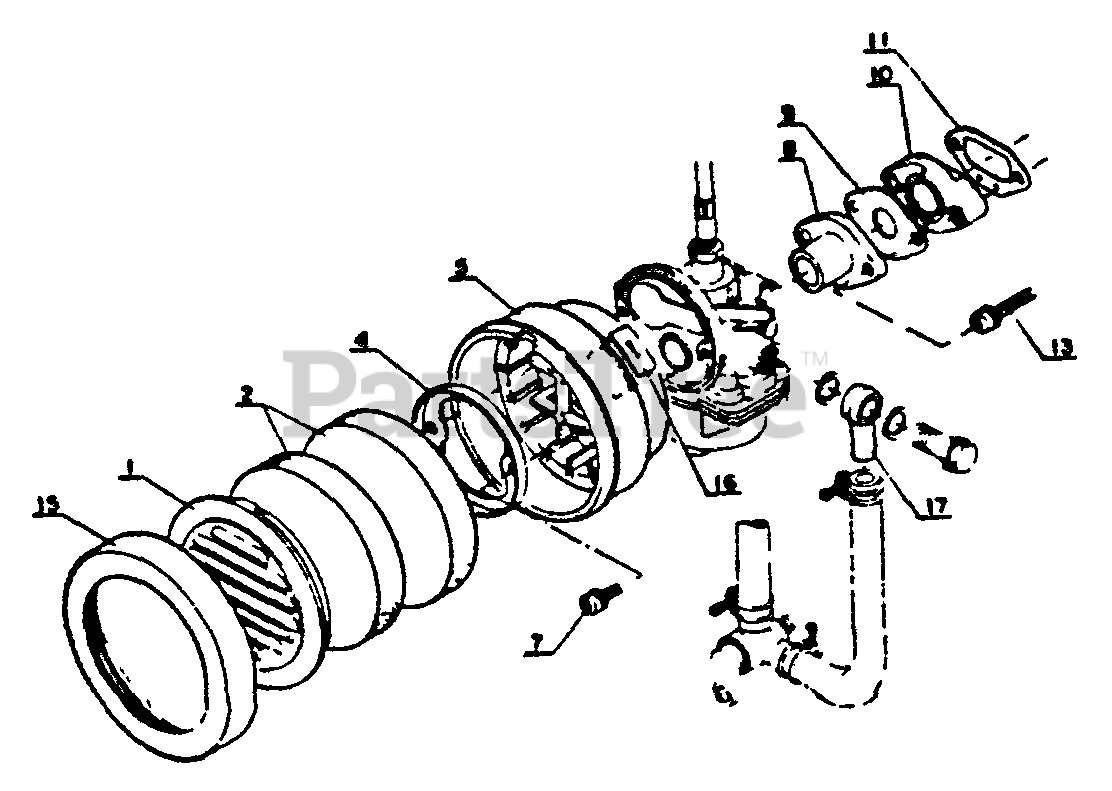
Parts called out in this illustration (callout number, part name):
1	COVER, AIR FILTER
2	FILTER, AIR
4	BRACKET, AIR CLEANER
5	CASE, AIR FILTER
7	SCREW - 4X10
8	ADAPTOR, INTAKE
9	GASKET, INTAKE
10	INSULATOR, INTAKE
11	GASKET, INTAKE
13	SCREW - 4X25
15	COVER, AIR FILTER
16	LABEL - CHOKE
17	CONNECTOR
